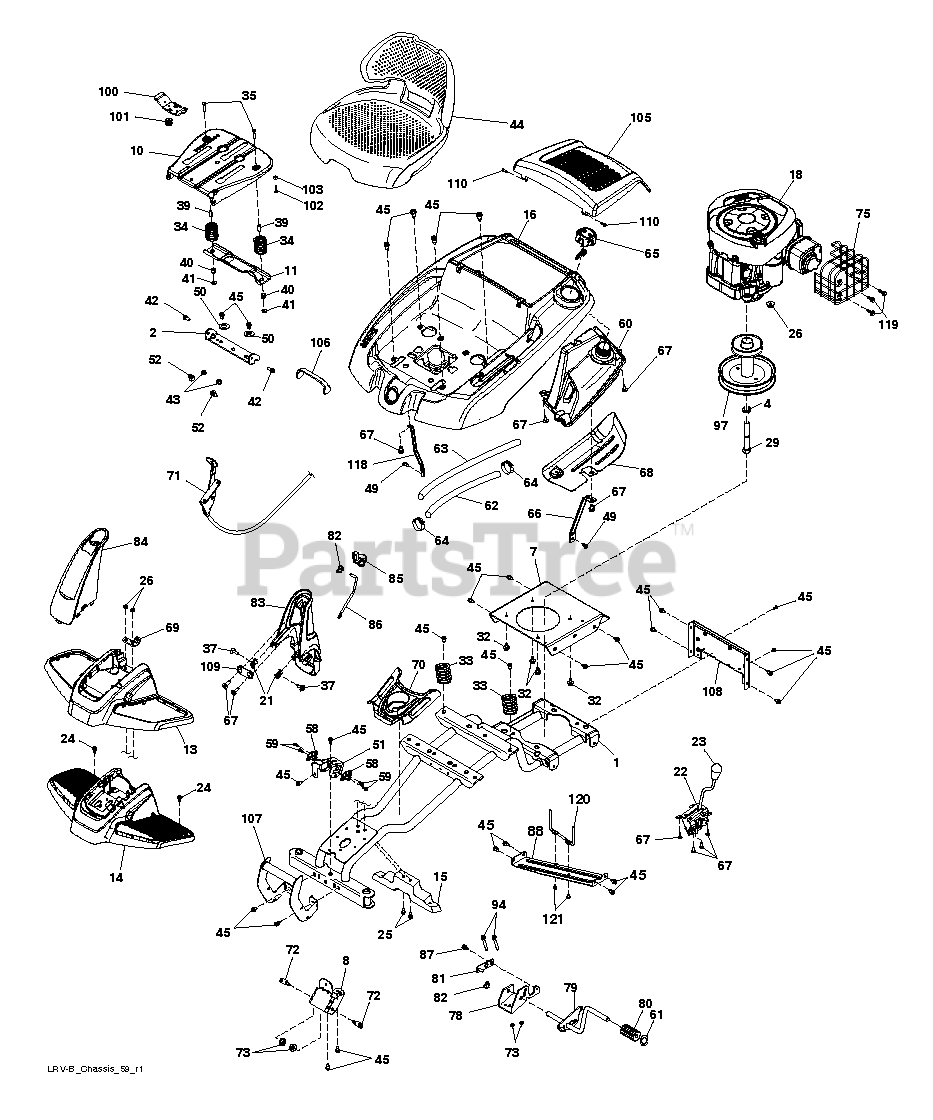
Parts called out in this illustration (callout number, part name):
2	BRKT.PIVOT.FENDER
4	LOCKWASHER
8	BRACKET.SUSP.CHAS.FR.LRV
10	PAN.ASM.SEAT.SHORT.SLD.ADJ.TEX
11	BRKT.MNT.OPC.SW.SEAT.
13	COVER.AESTH.FOOTREST.MS428
14	FOOTREST.STRUCTURAL.
15	SUPPORT. FOOTREST.LRV.MS428
16	PANEL CONTROL ASM.LRVB.GEARDRV
21	Speed Nut, U-Type
22	Clutch Deck Assembly, LRVB
23	KNOB.OVAL.CUSTOM.BLACK
24	SCREW.#10 X 0.750.BOS (2 2)
25	BOLT.CARRIAGE
26	NUT
29	Hex Bolt, 7/16-20 X 3.0 Gr5 Yellow
32	SCREW.3/8-16
33	Compression Spring, Seat Black
34	SPRING COMPRESSED
35	BOLT.ROUND.HEAD.SQUARE.NECK
37	SCREW.PAN.HEAD.#10
39	SPACER SPLIT 28X.96
41	NUT T
42	Shoulder Bolt, 5/16-18 X 5/8
43	NUT.71038.31-18.HEX.NYLOCK
44	COMFORT.SEAT.ASSEMBLY
45	SCREW
49	SCREW 5/16-18X1
51	STEERING.BRACKET.PNT
52	PUSH CLIP
58	Rack Bushing, LRVB
59	SCREW.1/4-20X5/8
60	LRVB.FUEL.TANK.ASSEMBLY.EPA
61	NUT.PUSH.50".BLACK
63	RP PURGE LINE
64	HOSE CLAMP
65	CAP.FUEL.2 WAY VENT
67	SCREW.#10 X 0.500
70	CONSOLE.CENTER.CUPHOLDER
72	STUD.FASTNER.W/ANTI-ROTATE
73	NUT LOCK HEX FLANGE 5/16-18
75	GUARD.LRVB.MUFFLER
80	COVER.PEDAL.BRAKE.LRV
82	RETAINER CLIP
83	COLUMN.R.STEERING.ASM
84	COVER.ASM.BOOT.STEER.FRT LRVB
87	BOLT.SHOULDER.5/16-18X
88	BRACE.LOW.LRVB.PMST.PLATEX431
94	BOLT HEX FLGHD 5/16-18X3 GR. 5
97	PULLEY.ENGINE.LRVB.PMST
100	HANDLE.SLIDE.SEAT.TEX.BLACK
101	SPRING.LATCH.SEAT.TEX
103	WASHER 13/32 X 2-3/8 X 12GA
105	Engine Cover, Lrvb Pattern 2.X428
106	STRAP.BATTERY.LRVB
107	WELDMENT.FRT.PNT.BRUSHGAD.LR
108	COVER.REAR.LRVB.PMSTX431
119	SCREW NO 8-18 X 1/2;HEX WASHER
120	KEEPER.PNT.GEARDRV.LRV.ENG.BLT
121	SCREW 1/4X20
